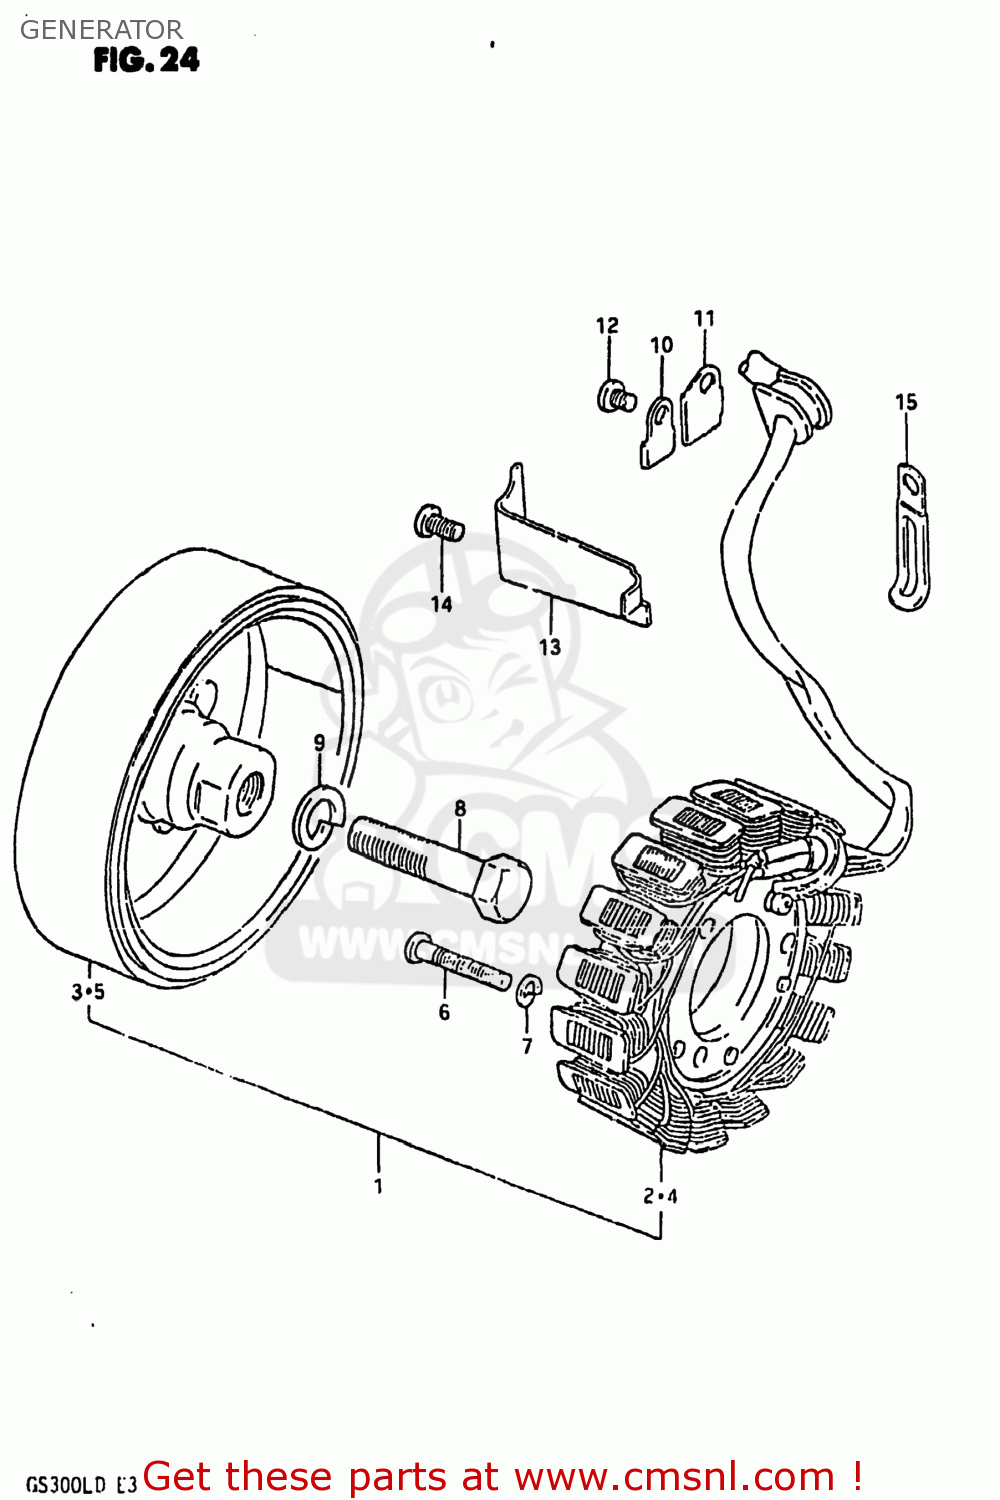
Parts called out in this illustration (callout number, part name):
1	GENERATOR ASSEMBLY
2	STATOR ASSEMBLY
3	ROTOR ASSEMBLY
4	STARTER ASSY
5	ROTOR ASSY
6	SCREW
7	LOCK WASHER
8	BOLT 12X45
9	WASHER,LOCK 12
10	CLAMP,GENERATOR LEAD WIRE
11	CLAMP,GENERATOR LEAD WIRE
12	SCREW
13	CLAMP,GENERATOR LEAD WIRE
14	SCREW
15	CLAMP L:35
